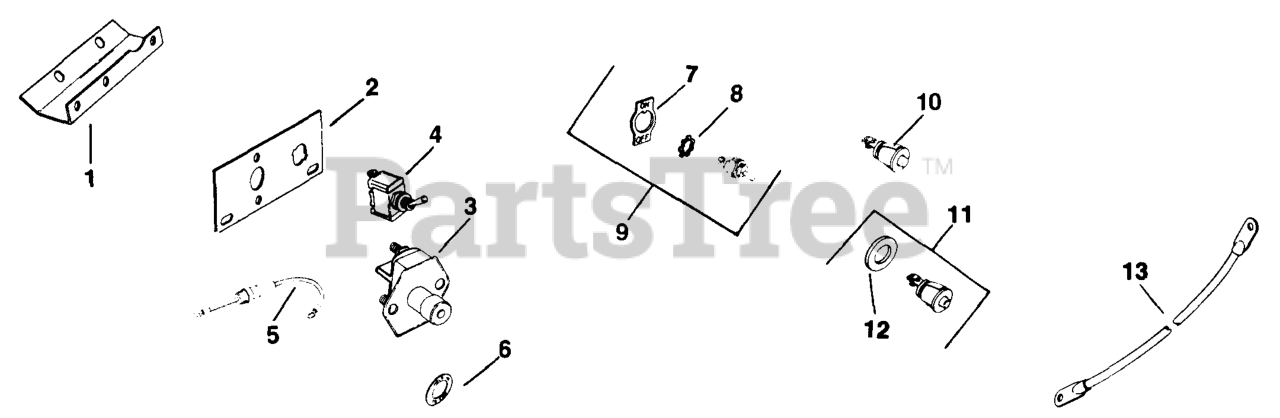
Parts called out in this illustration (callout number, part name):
4	SWITCH - DISCONTINUED
5	HOLDER
11	KIT, SWITCH
12	FLAT WASHER
4130401-S	FUSE
